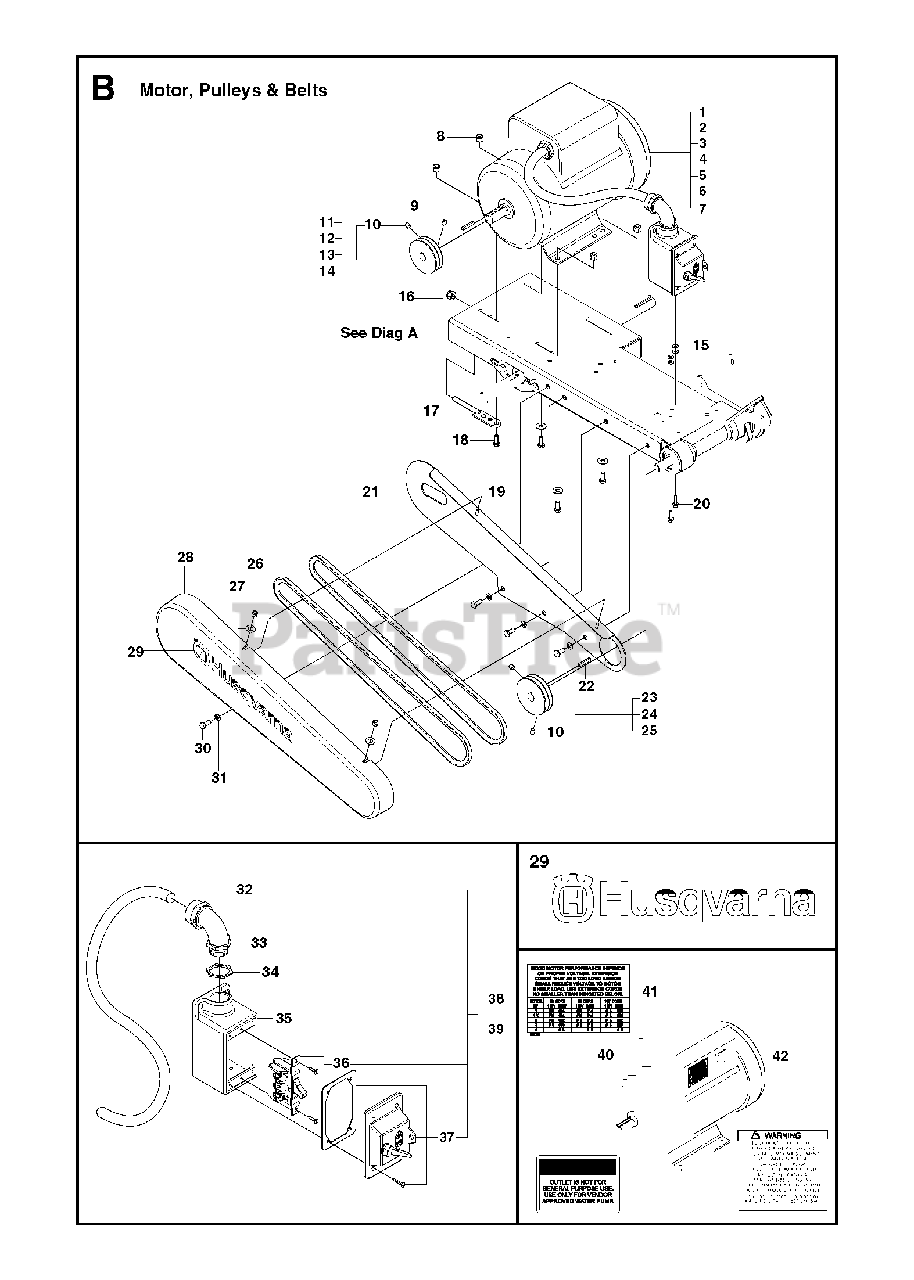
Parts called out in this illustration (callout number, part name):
5	MOTOR5HP 60Hz-3Ph 575V
8	NUT
13	PULLEY 2G3V3.0 - .875 W/SS"14"" -60Hz"
14	PULLEY"14"" -50Hz 2-Piece Pulley"
16	NUT
23	PULLEY 2G3V3.35 - .75 W/SS"14-20"" -60Hz"
25	PULLEY"14"" -50Hz 2-Piece Pulley"
26	NUT
30	SCREW
31	WASHER
38	SWITCHCompl (1-Phase)
39	SWITCH, ASSY DUST PROOF W/WIRECompl (3-Phase)
